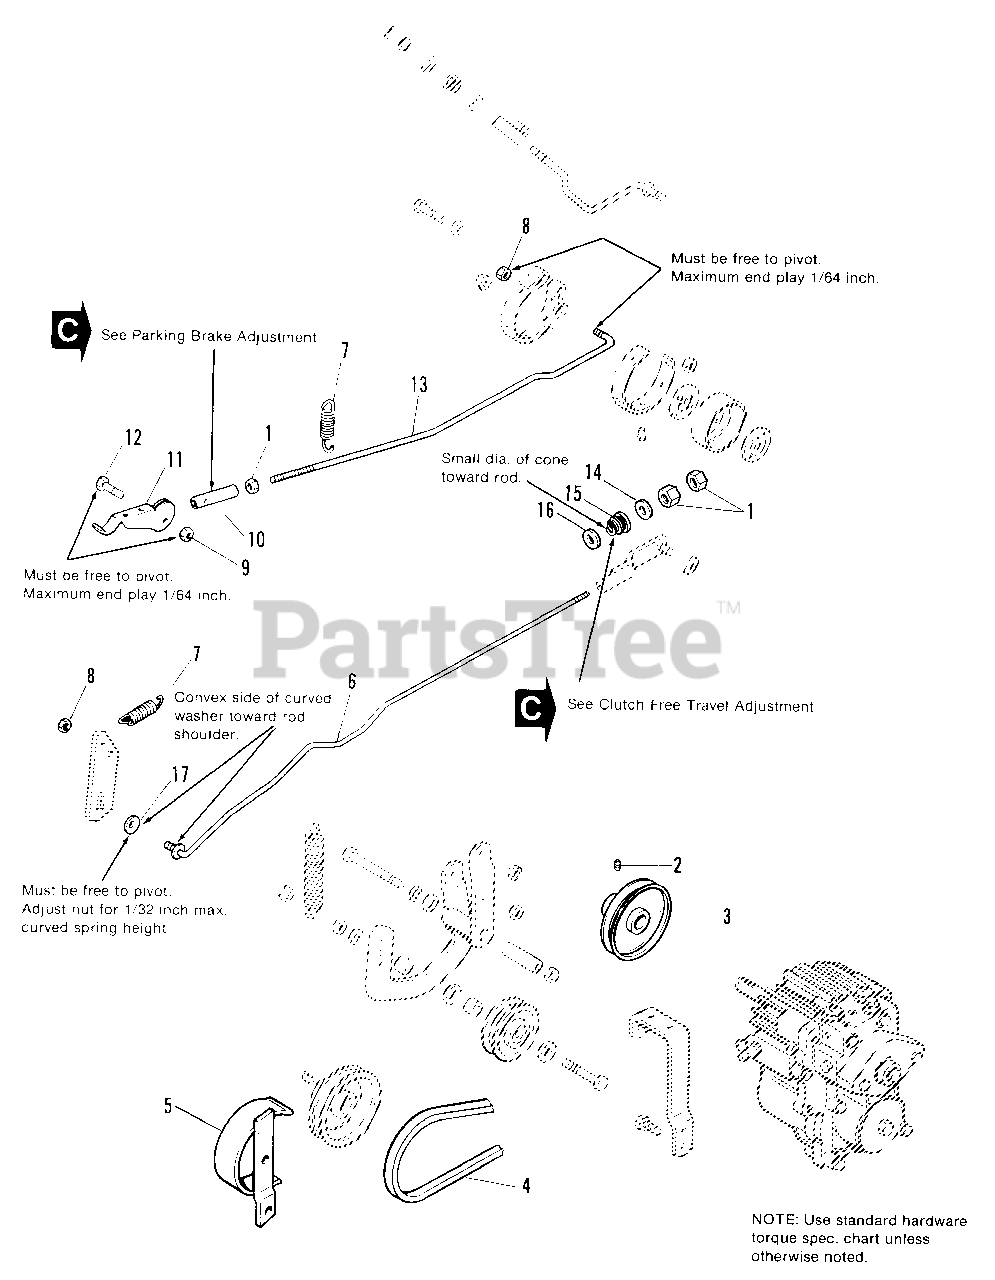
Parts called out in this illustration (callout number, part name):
1	NUT, Hex, Full, 5/16-18
2	SETSCREW, 5/16-18 x 3/8
3	PULLEY, Drive, Transmission
4	V-BELT, Drive, Transmission
5	GUARD ASSY.
6	ROD, Clutch
8	LOCKNUT, Hex, 5/16-18
9	LOCKNUT, Hex, 1/4-20
11	LEVER, Parking Brake
12	CAPSCREW, Hex Hd., 1/4-20 x 1
14	WASHER, 5/16
15	SPRING, Cone
17	WASHER, Curved, Spring
